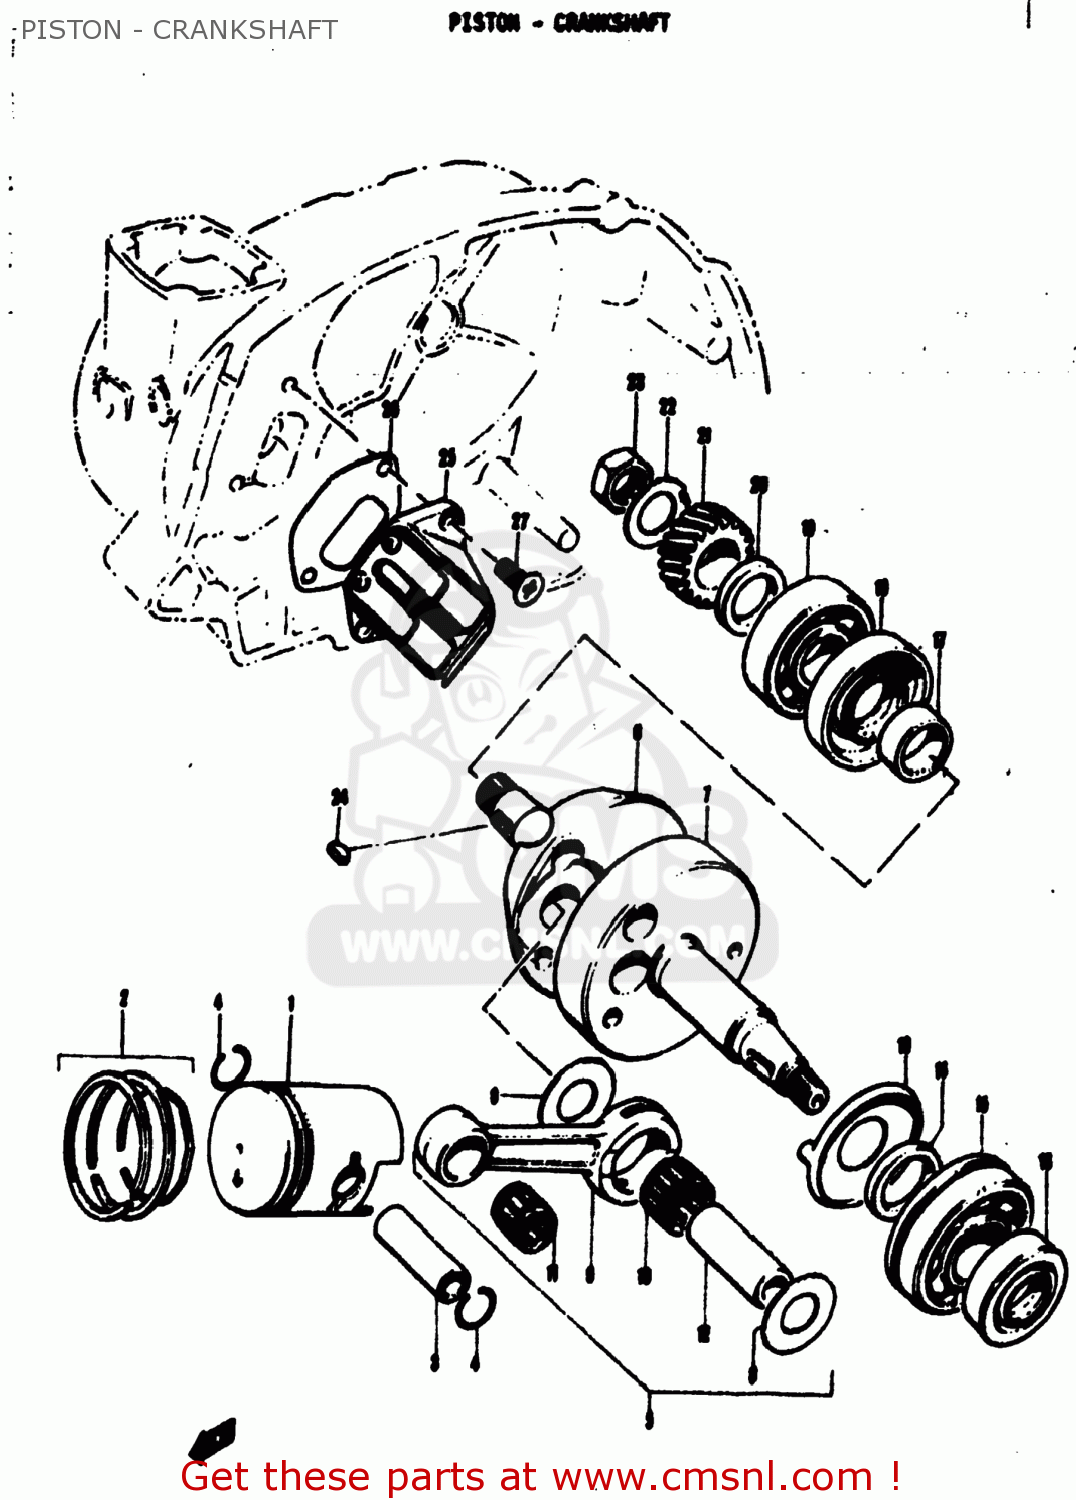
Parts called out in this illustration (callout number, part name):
1	PISTON (41.00MM)
2	RING SET, PISTON
3	PIN,PISTON
4	RING,SNAP
5	CRANKSHAFT ASSY
8	WASHER(16X32X1)
9	CONNECTING ROD
10	BEARING
11	BEARING
12	PIN,CRANK
13	PLATE,CSHAFT OIL GUIDE
14	SPACER(20X28X4.5)
15	BEARING(20X47X14)
16	OIL SEAL
17	SPACER(17X23X9)
18	SEAL,OIL(22.2X47X8)
19	BEARING
20	SPACER(17.2X27X4.5)
21	GEAR,PRIMARY DRIVE NO.21
22	WASHER
23	NUT
24	KEY
25	REED VALVE ASSY
26	GASKET,REED VALVE
27	SCREW
